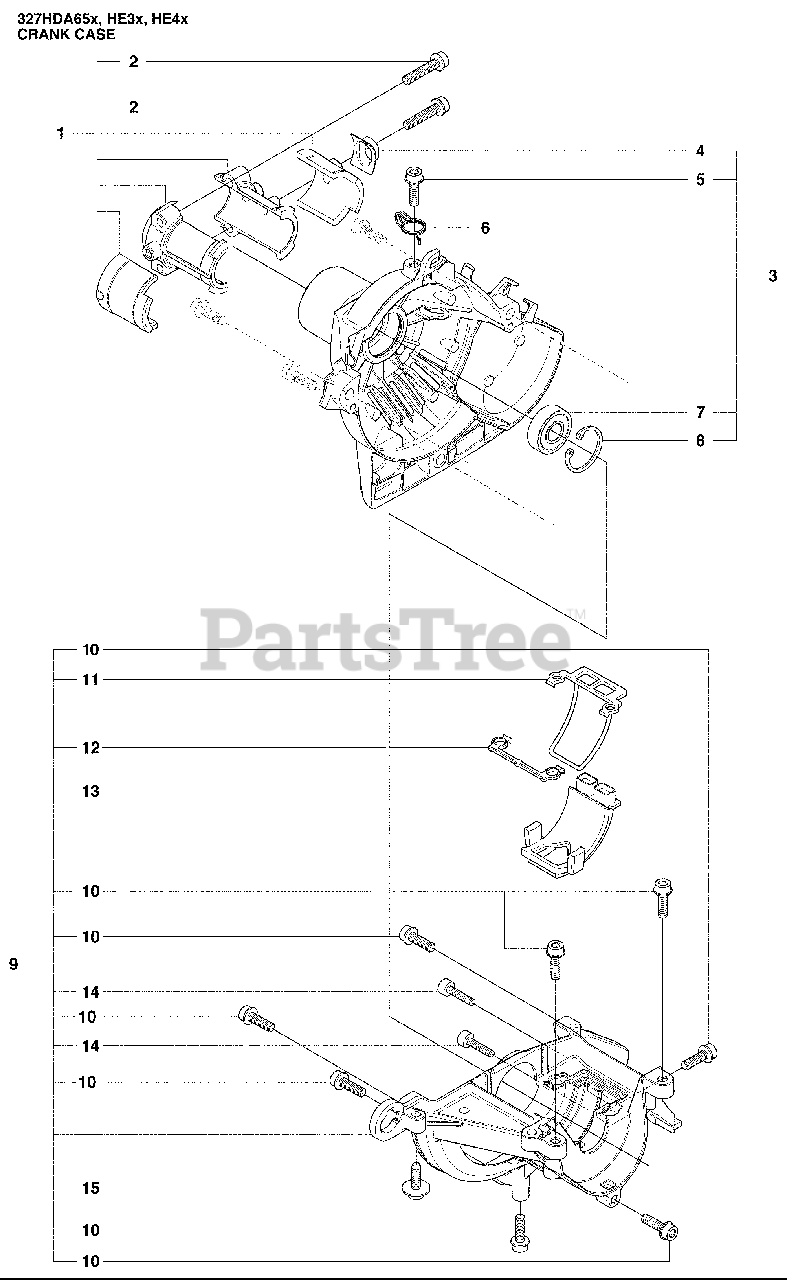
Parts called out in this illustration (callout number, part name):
1	Compresion Sleeve and Isolator Set
3	Clutch Cover
4	Protection Plate
5	Screw, Ihscfm
8	Retaining Ring
10	Screw, Ihscfm
